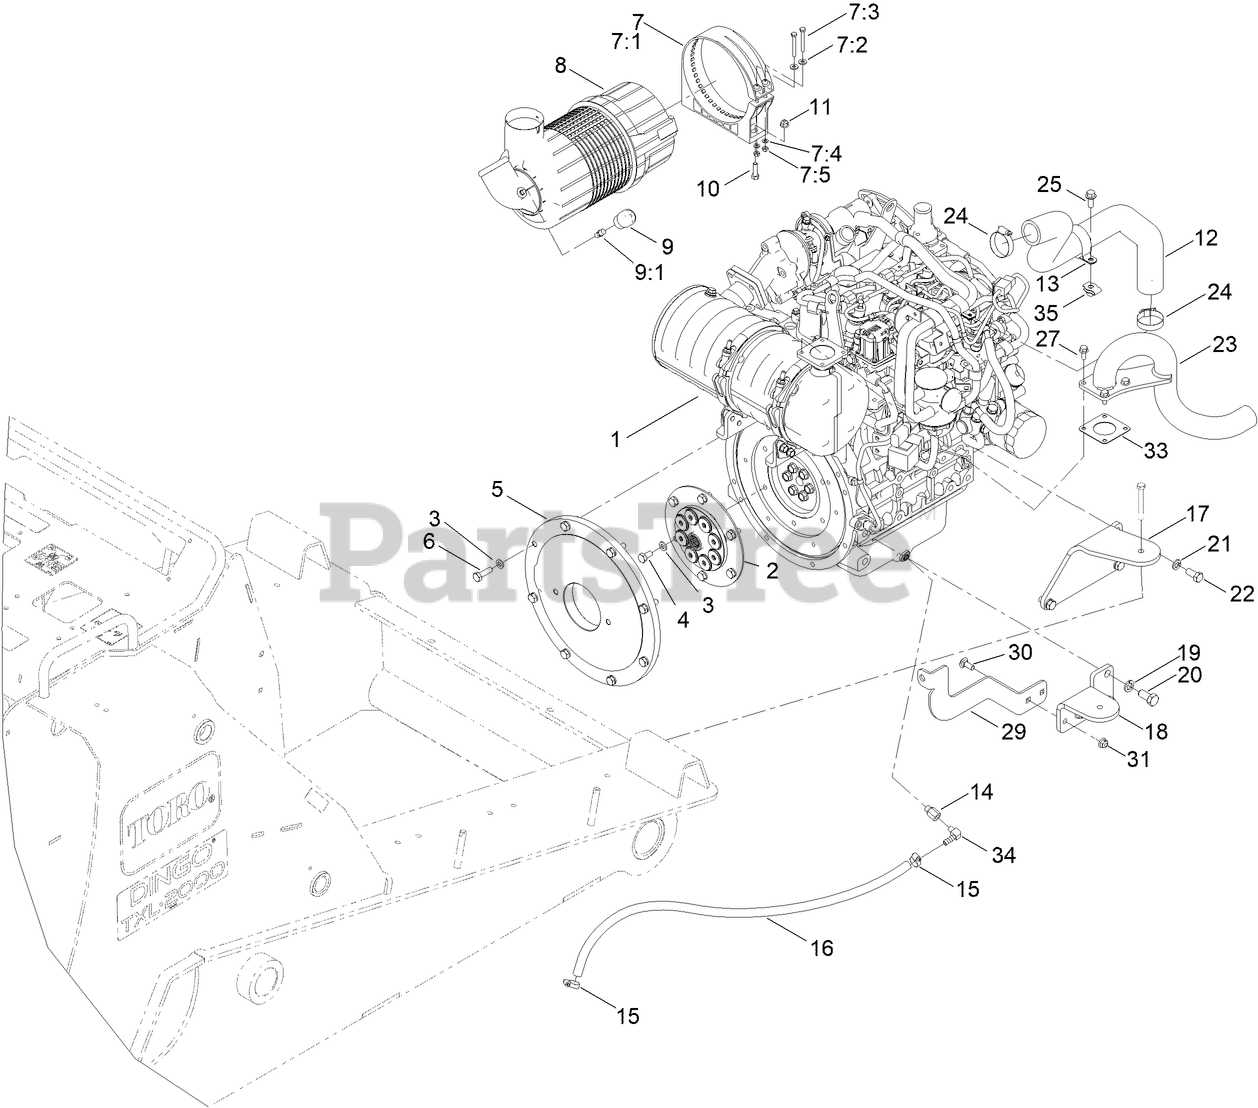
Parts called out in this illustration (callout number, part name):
1	ENGINE-KUBOTA
2	COUPLER-SPRING, FLYWHEEL
3	WASHER-HARDENED
5	PLATE-FLYWHEEL
6	SCREW-HH
7	STRAP-CLEANER, AIR
7:1	SPRING
7:2	WASHER-FLAT
7:3	SCREW-HH
7:4	WASHER-FLAT
7:5	NUT-LOCK
8	AIR CLEANER ASM
9	INDICATOR
9:1	ADAPTER-INDICATOR
10	SCREW-HH
11	NUT-HF, NI
12	HOSE-AIR, COOLER
13	CLAMP-R
14	ADAPTER-DRAIN
15	CLAMP-HOSE
16	HOSE-DRAIN
17	MOUNT-ENGINE
18	MOUNT-ENGINE
19	WASHER-LOCK, SPRING
20	SCREW-HH
21	WASHER-LOCK
22	SCREW-HH
23	PIPE-EXHAUST
24	CLAMP-HOSE
25	SCREW-HHF
27	SCREW-HHF
29	BRACKET-PUMP, RH
30	BOLT-CARR
31	NUT-HF, NI
33	GASKET-MUFFLER
34	FITTING-90 DEG
35	NUT-TINNERMAN
